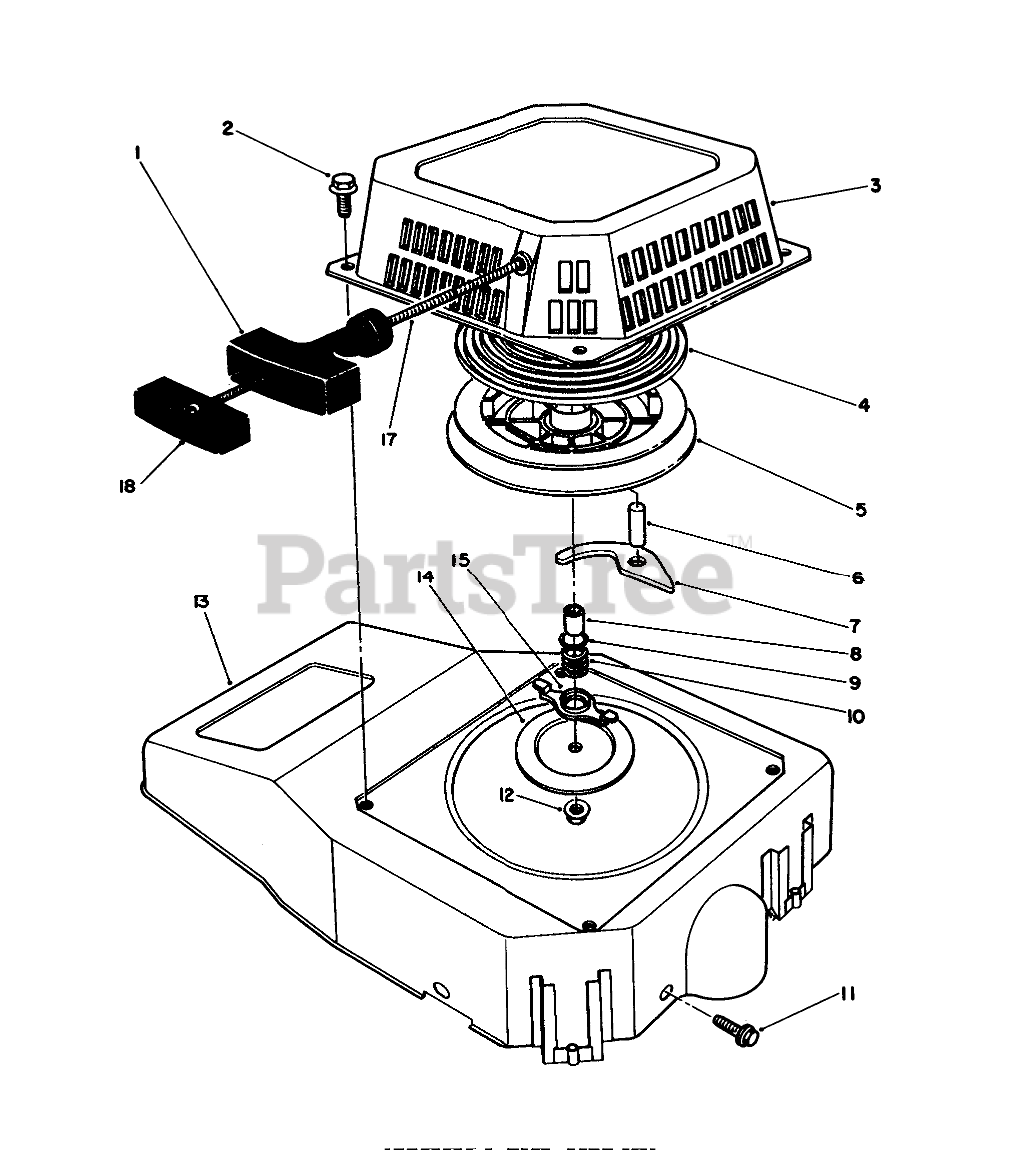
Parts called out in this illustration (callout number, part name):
1	HANDLE
2	SCREW-HHF
3	Case-Recoil
4	SPRING
8	Spacer
9	WASHER
10	Spring-Friction
13	SHROUD
14	PLATE
15	Guide-Paw
17	ROPE-STARTER
18	RETAINER HANDLE
